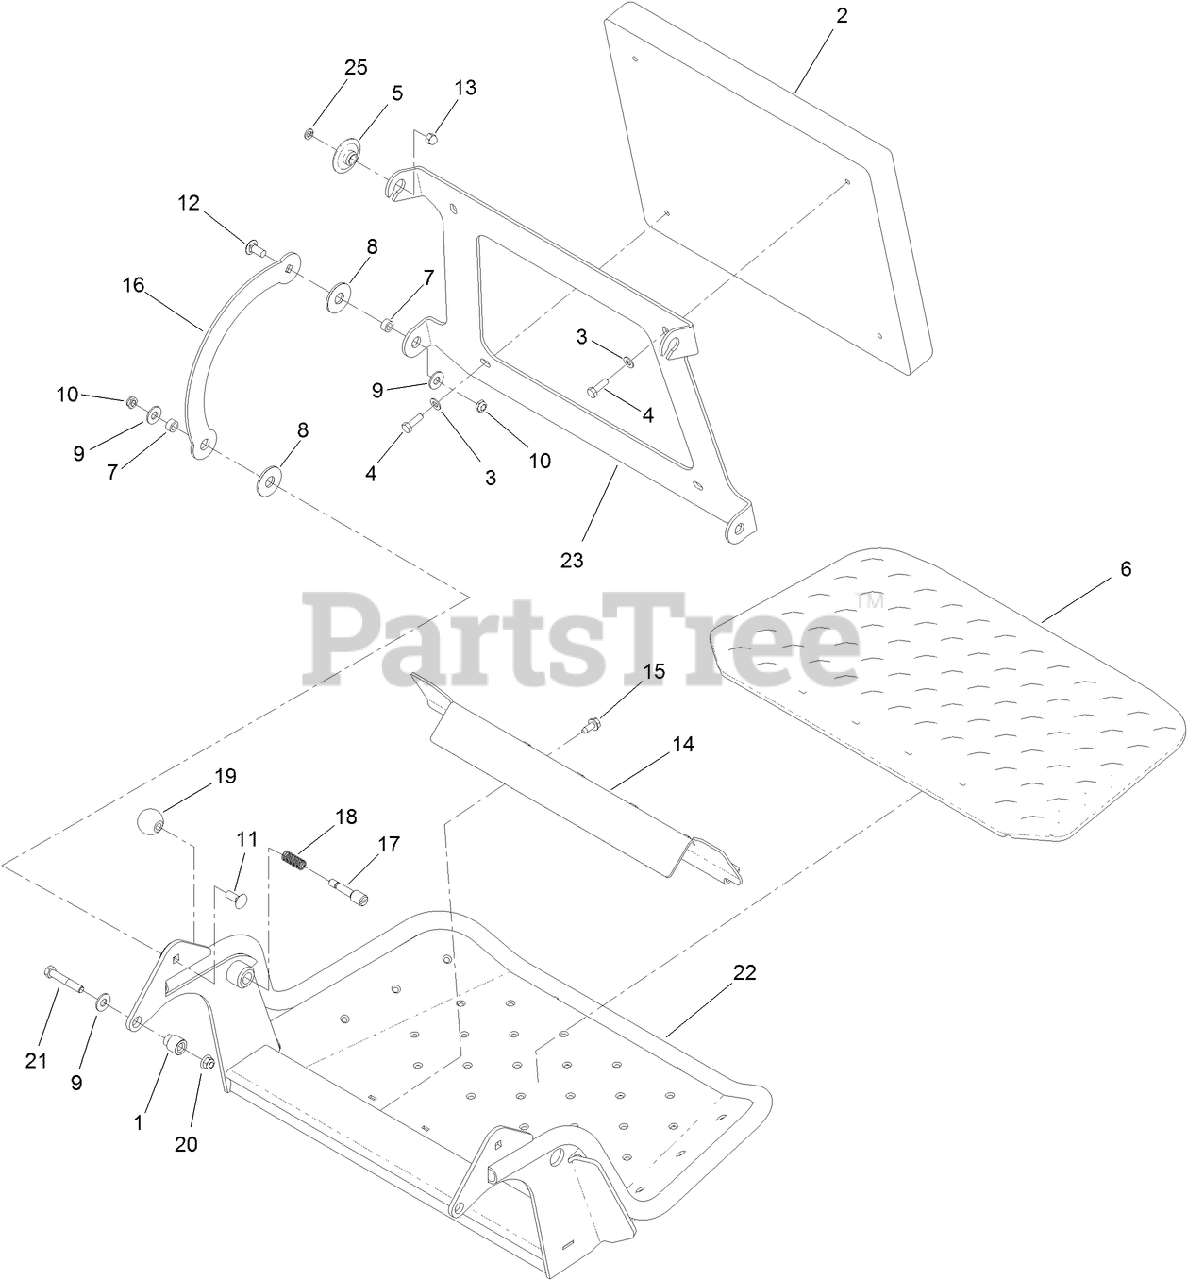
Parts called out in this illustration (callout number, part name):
1	BUSHING-FLANGED
2	PAD-CUSHION
3	WASHER-PLAIN
4	SCREW-HH
5	SLIDE-BUSHING
6	MAT-PLATFORM
7	SPACER
8	WASHER-FRICTION, COMPOSITE
9	WASHER-FLAT
10	NUT-LOCK, NI
11	BOLT-CARR
12	SCREW-CARR
13	NUT-ACORN
14	CLAMP-SHIELD
15	SCREW-HWHTF
16	LINK-PAD
17	PIN-LATCH
18	SPRING
19	KNOB-BALL
20	NUT-HF, NI
21	SCREW-HH
22	PLATFORM ASM
23	HINGE-PAD
25	WASHER-LOCK
